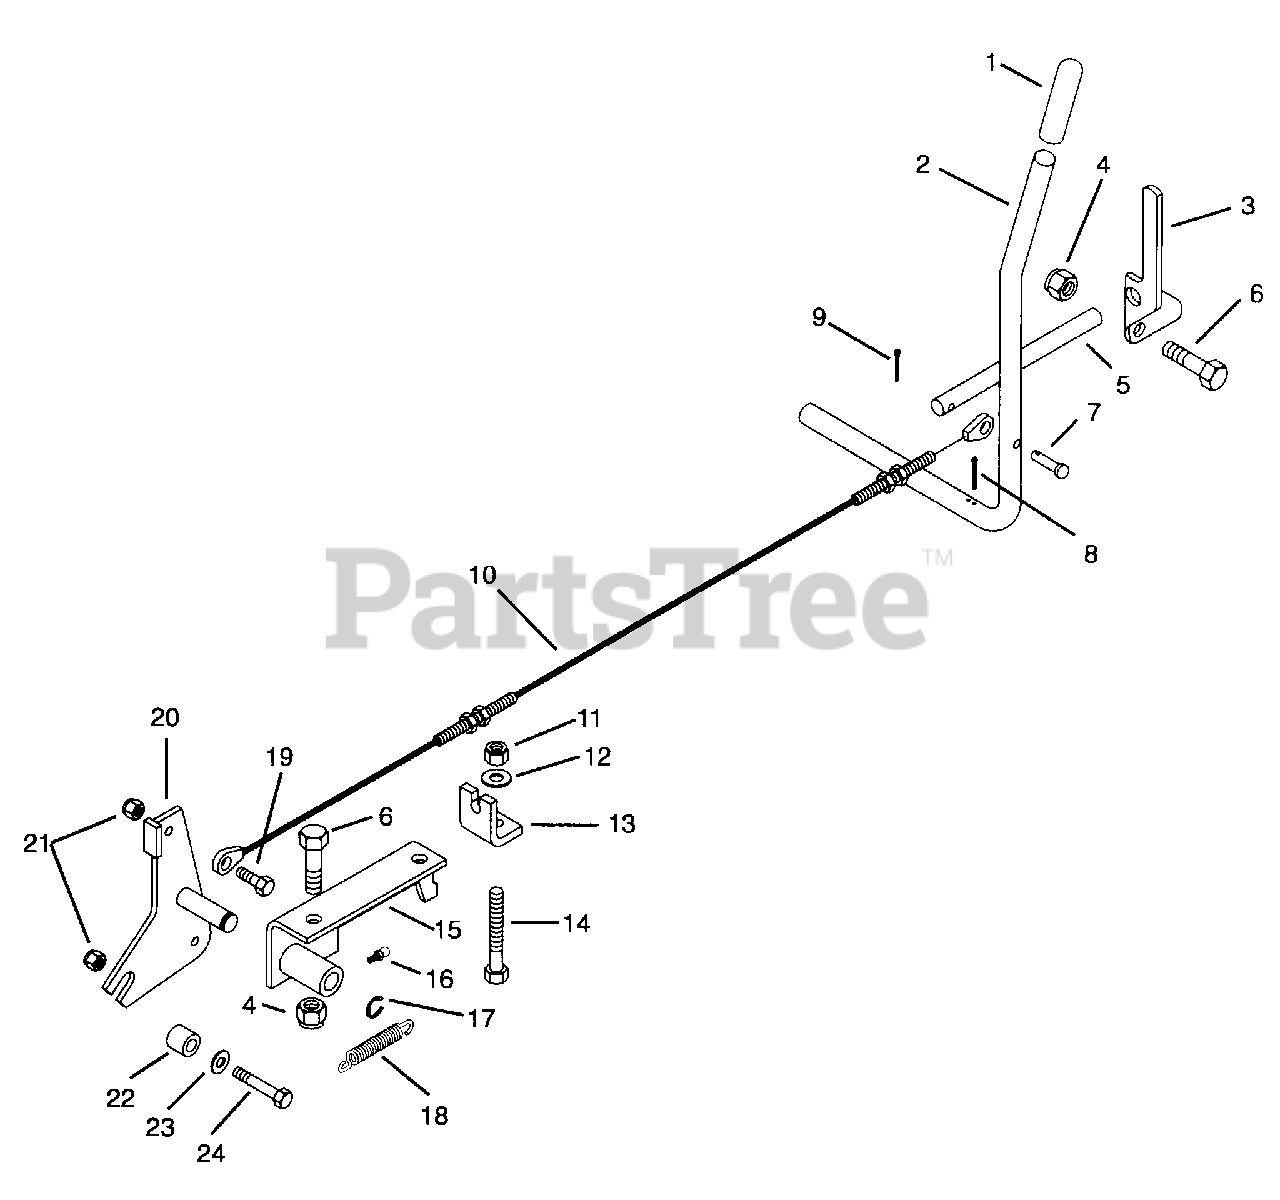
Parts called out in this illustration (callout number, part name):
1	Grip, Handle
2	Lever, Brake
3	Arm, Parking Brake Lock
4	Nut-Locking-Center .38-16
5	Rod, Brake Lock
6	Bolt-Hex .38-16 x 1.00 Grade 5
7	Pin-Clevis .25 x 1.75
8	Pin-Cotter .094 x 1.00
9	Pin-Cotter .09 x .75
10	Cable, Brake
11	Nut-Locking-Center .31-18
12	Washer-Flat-Steel .344 x .688 x .065
13	Bracket, Cable
14	Bolt-Hex .31-18 x 1.00 Grade 5
15	Weldment, Brake Pivot
16	Fitting-Lube .25-28 x .256
17	Ring-Retaining-External .392 x .042
18	Spring-Tension .093 x .75 x 4.0
19	Bolt-Hex .25-20 x .75
20	Weldment, Brake Arm
21	Nut-Locking-Center .25-20
22	Bushing, Sleeve .260 x .500 x .750
23	Washer-Flat-Steel .281 x .620 x .065
24	Bolt-Hex .25-20 x 1.75 Grade 5
